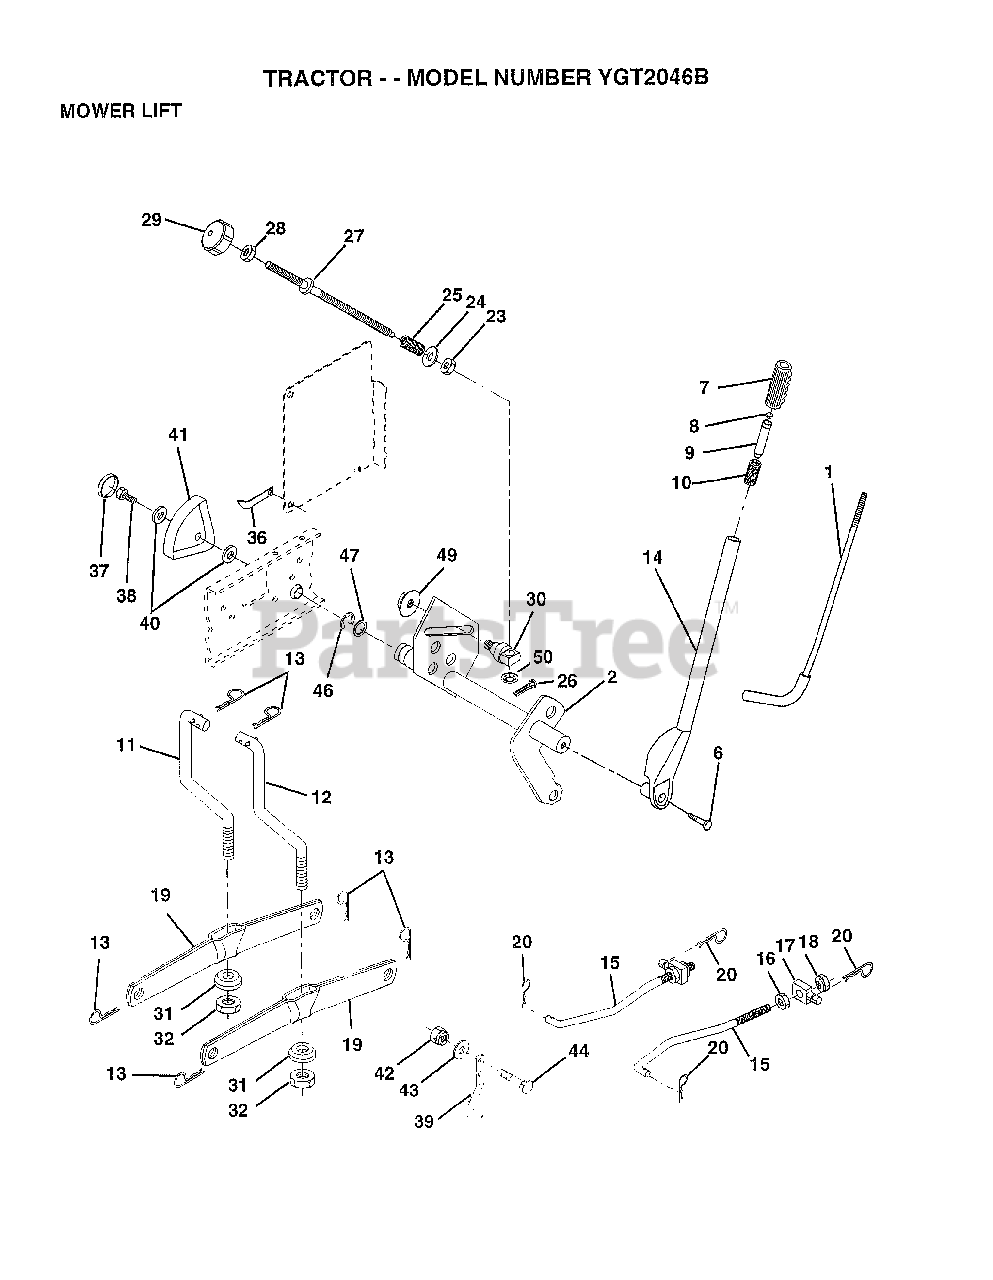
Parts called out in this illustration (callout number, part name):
1	LEVER ROD LT
2	SHAFT LIFT W/IND
6	"BOLT,HEX"
7	GRIP HANDLE
10	SPRING T
11	LINK.LIFT.LH.GTV
12	LINK.LIFT.RH.GTV.
15	LINK.FRONT
16	NUT
17	TRUNION
18	NUT.LK.W/WSH.1/2.
19	ARM SUSP REAR
20	RETAINER.SPRING
23	NUT T
24	WASHER
25	SPRING.COMP.INF.H
27	ROD.ADJ.LIFT
28	NUT
29	KNOB INF 3/8-16
30	TRUNNION
31	BEARING PVT LH
32	NUT.CROWNLOCK.3/8
36	POINTER HEIGHT INDICATOR
37	"PLUG,HOLE"
38	SCREW
39	STOP.OVER.CENTER
40	WASHER
41	HEIGHT INDICATOR
43	WASHER GT
44	BOLT
46	E-RING
47	WASHER
49	NUT.HXFLG.LOCK.
